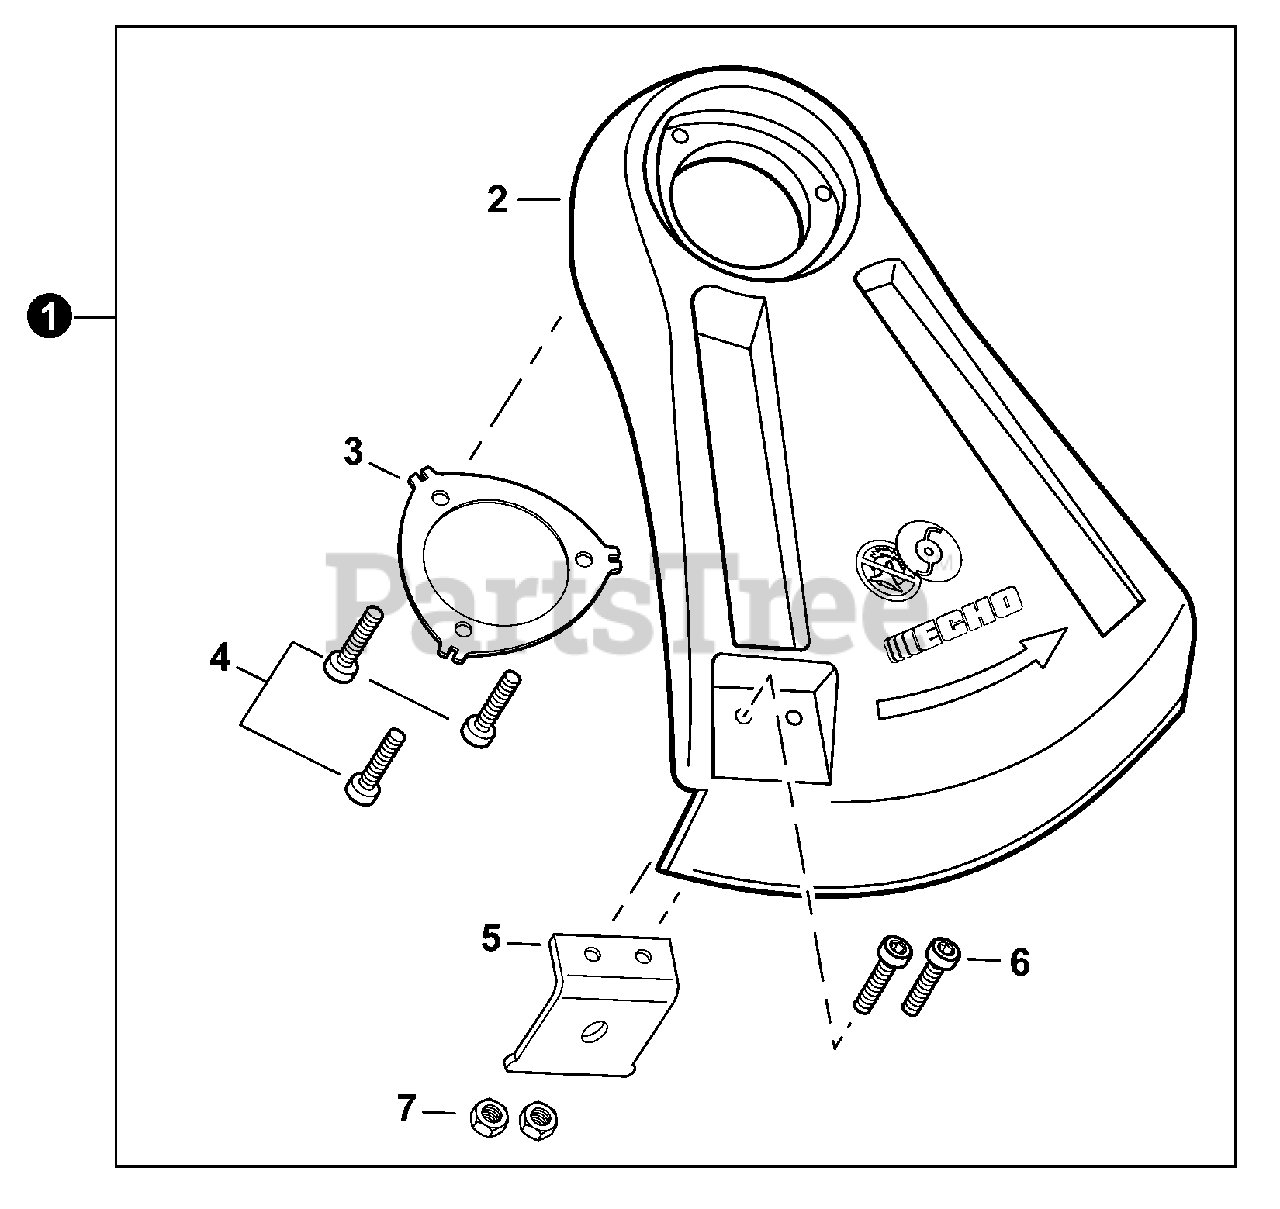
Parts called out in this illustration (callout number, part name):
1	SHIELD KIT, DEBRIS
2	SHIELD, DEBRIS PLASTIC
3	PLATE, SHIELD
4	BOLT, TORX 5x16
5	CUTTER, LINE
6	BOLT, TORX 5x12
